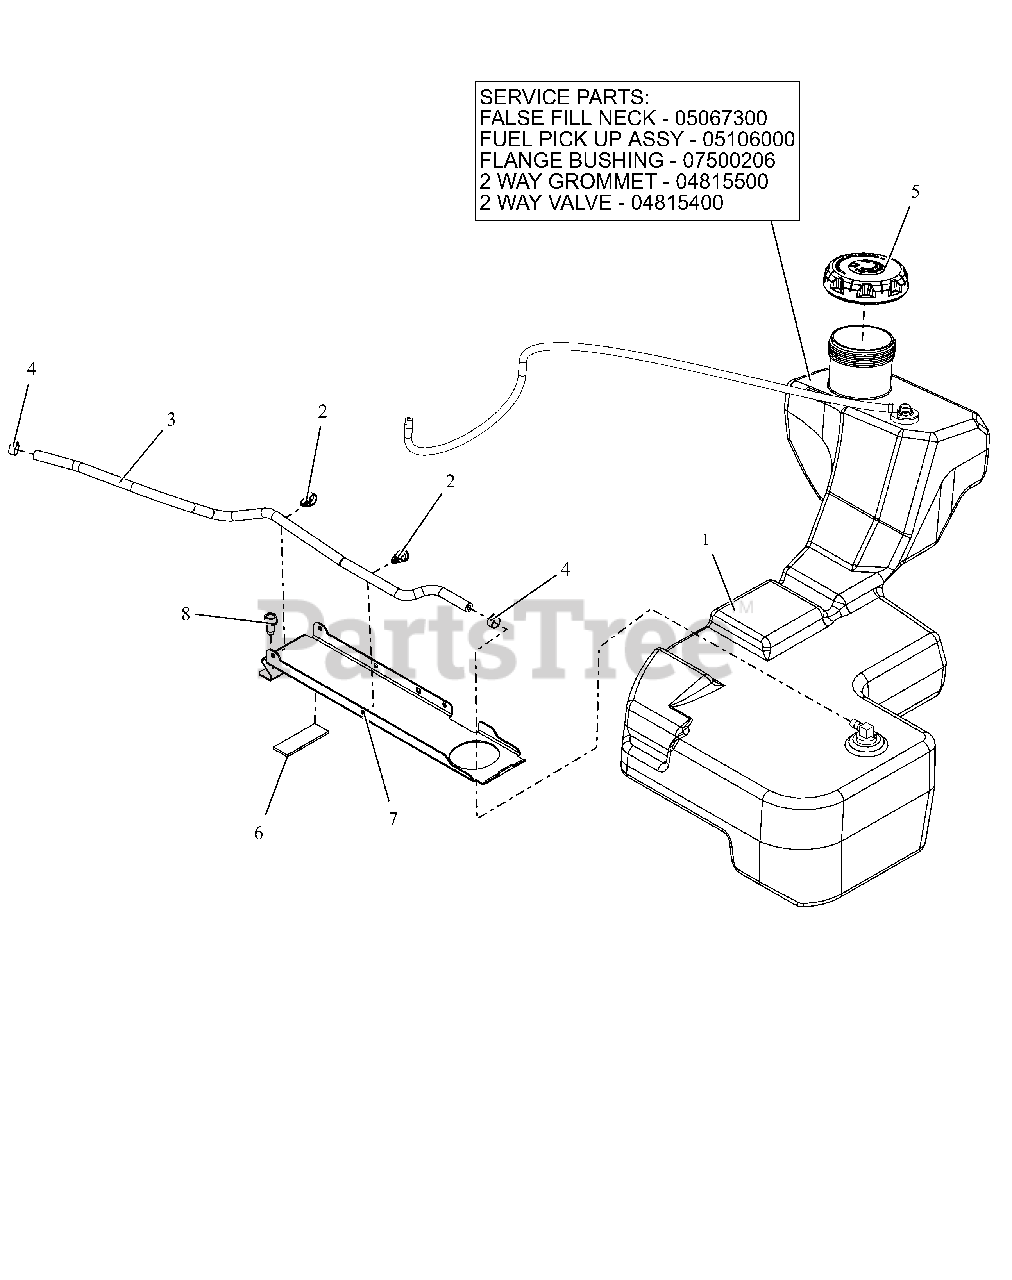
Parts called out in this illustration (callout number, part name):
1	ASSY, FUEL TANK-HD
1	INSERT, FUEL NECK FALSE FILL
1	ASM, HD FUEL PICK-UP
1	BSHG-FLG .375X1.062X.625 NITR
1	GROMMET, 2-WAY
1	VALVE, 2-WAY
2	ROUTING CLIP (1/2" ID)
3	HOSE, .25 LOW-PERM BULK GAS
4	CLAMP, FUEL LINE
5	CAP, FUEL VENTIN AUTOLOCK
6	PAD,RBR 1.0"X3.0" W/ADHESIVE
7	BRKT, FUEL TANK HOLD DOWN
8	SCR,TAP .375-16X.75 HWH TR ZCC
